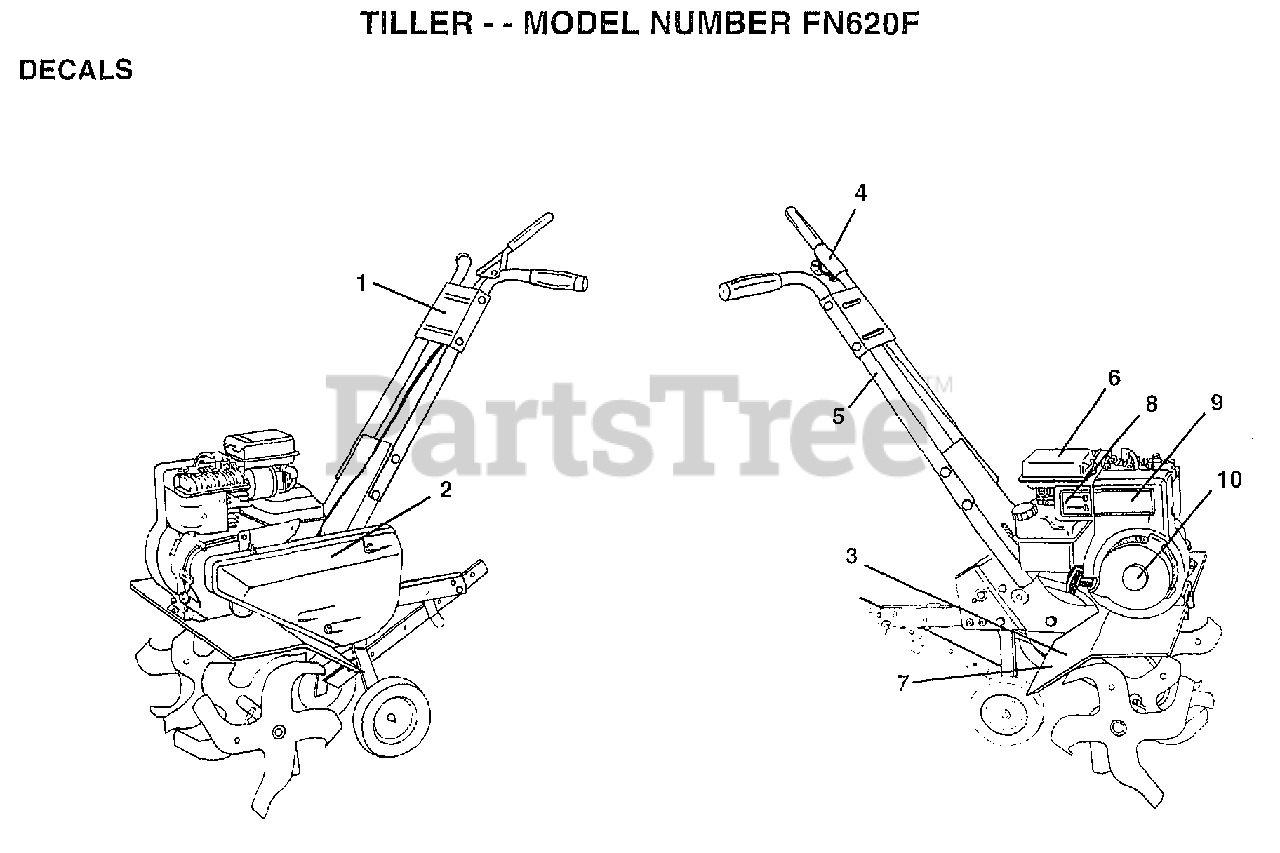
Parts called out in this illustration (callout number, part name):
1	DECAL HANDLE BRKT
3	DECAL.CAUTION
4	DECAL TI
5	DECAL TI
6	DECAL TI
8	DECAL-SPEED CONTROL
9	DECAL-BRIGGS AND STRATTON
10	DECAL-3.5 HP
